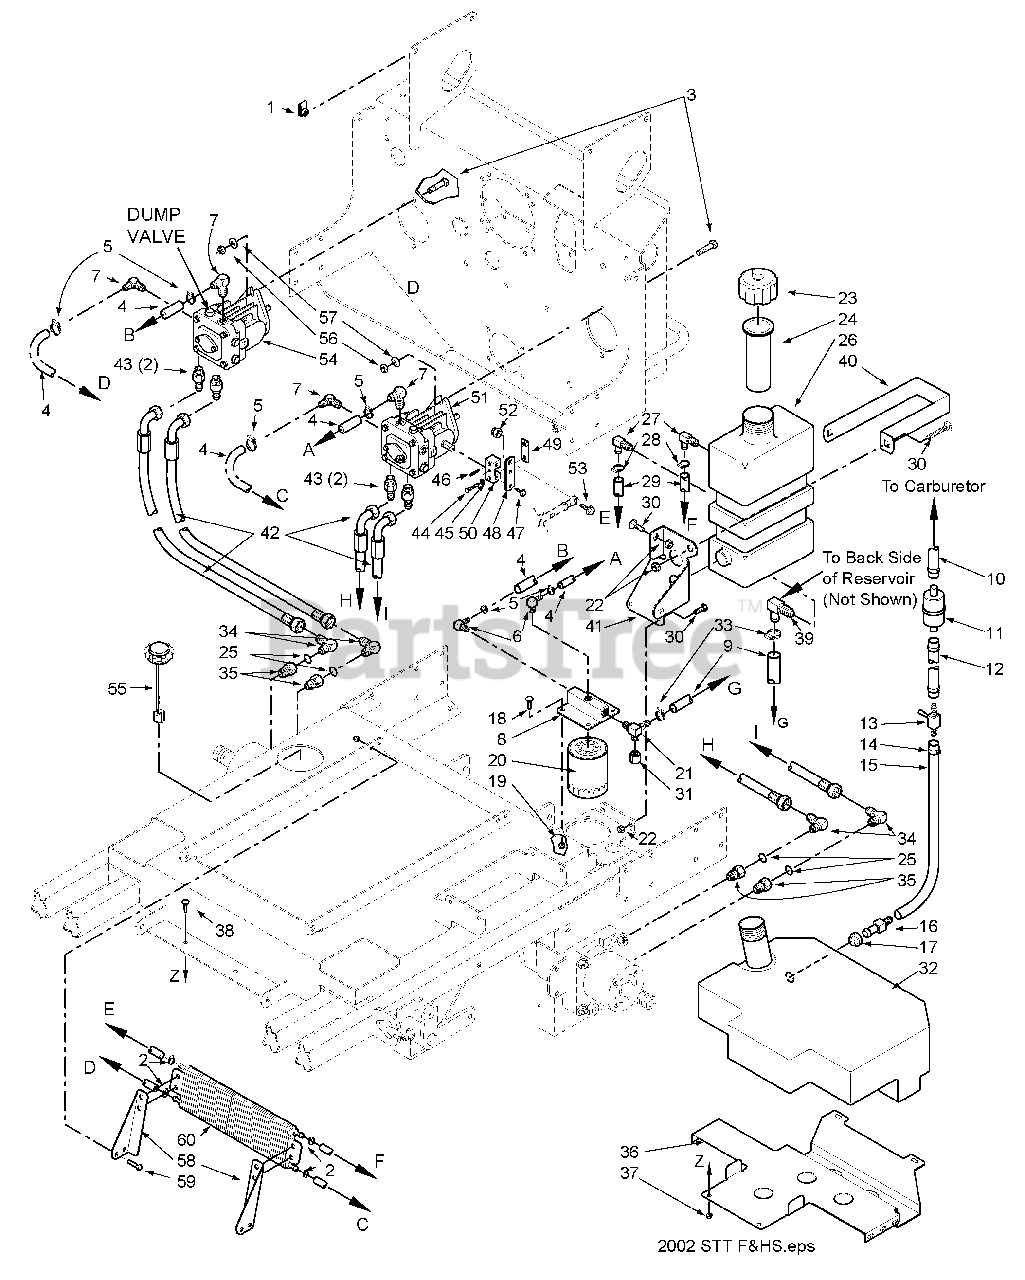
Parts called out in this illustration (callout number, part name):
1	U-Nut 1/4-20
2	Hose Clamp, 0.69 dia.
3	Bolt, Hex Head 1/4-20 x 2.0"
4	Hose, 3/8" ID Pushlock
5	Clamp, Hose 1/2"
6	Elbow, 90 Degree - 1/4 NPT x 3/8 Hose
7	Elbow, 90 Degree - 9/16 O-ring x 3/8 Hose
8	Oil Filter Base
9	Hose Assembly, 1/2" ID (Tank to Filter Base)
10	Fuel Hose to Carb.
11	Fuel Filter
12	Fuel Hose, 1/4" ID
13	Valve, Shutoff Kawasaki
14	Clamp, Fuel Hose
15	Fuel Hose, 1/4" ID
16	Hose Fitting
17	Bushing
18	Bolt, Hex Head 5/16-18 x1.0" Zinc
19	Nut, Serrated Flange 5/16-18
20	Oil Filter
21	Tee, 3/4 O-ring x JIC x 1/2" Hose
22	Nut, Hex Elastic Stop 1/4-20
23	Cap, Hydraulic Tank
24	Insert, Filler Neck
25	O-Ring
26	Oil Reservoir Assembly
27	Elbow, 90 Degree .38 Hose
28	Hose Clamp, 0.69 dia.
29	Hose, 3/8" ID, Pushlock
30	Screw, Phillips Head, 1/4-20
32	Fuel Tank Assembly
33	Clamp, Hose
34	Elbow, 90 Degree, 7/8-14 THD
35	Bushing, 7/8-14 JIC x 3/4-16 O-Ring
36	Support Bracket, Fuel Tank
37	Nut, 5/16-18 Serrated Flange
38	Bolt, Carraige 1/4-20 x 3/4"
39	Elbow, 90 Degree
40	Strap, Hydraulic Tank
41	Support Bracket, Hydraulic Tank
42	Hose Assembly, Pump
43	Union, 3/4-16 JIC x 3/4-16 O-ring
44	Bolt, Hex Head, 1/4-20 x 1-14"
45	Lockwasher, 1/4" Spring
46	Roll Pin, Spring 3/16 x 3/4"
47	Bolt, Hex Serrated Flange, 1/4-20 x 3/4"
48	Clamp, .69 Dia.
49	Clamp Plate, Pump Control
50	Block, Pump Control
51	Pump, Left Hand, BDP-16A-410
52	Nut, Hex, Elastic Stop 3/8-16
53	Bolt, Hex Head, 3/8-16 x 1-1/4
54	Pump, Right Hand, BDP 16A-307
55	Cap, Fuel Tank W/Guage
56	Nut, Hex Elastic Stop 3/8-16
57	Flatwasher, 3/8" (.391 x .938 x .105) Grade 8
58	Mounting Bracket - LH, Oil Cooler
59	Bolt, Hex Head 5/16-18 x 3/4"
60	Cooler, Oil
